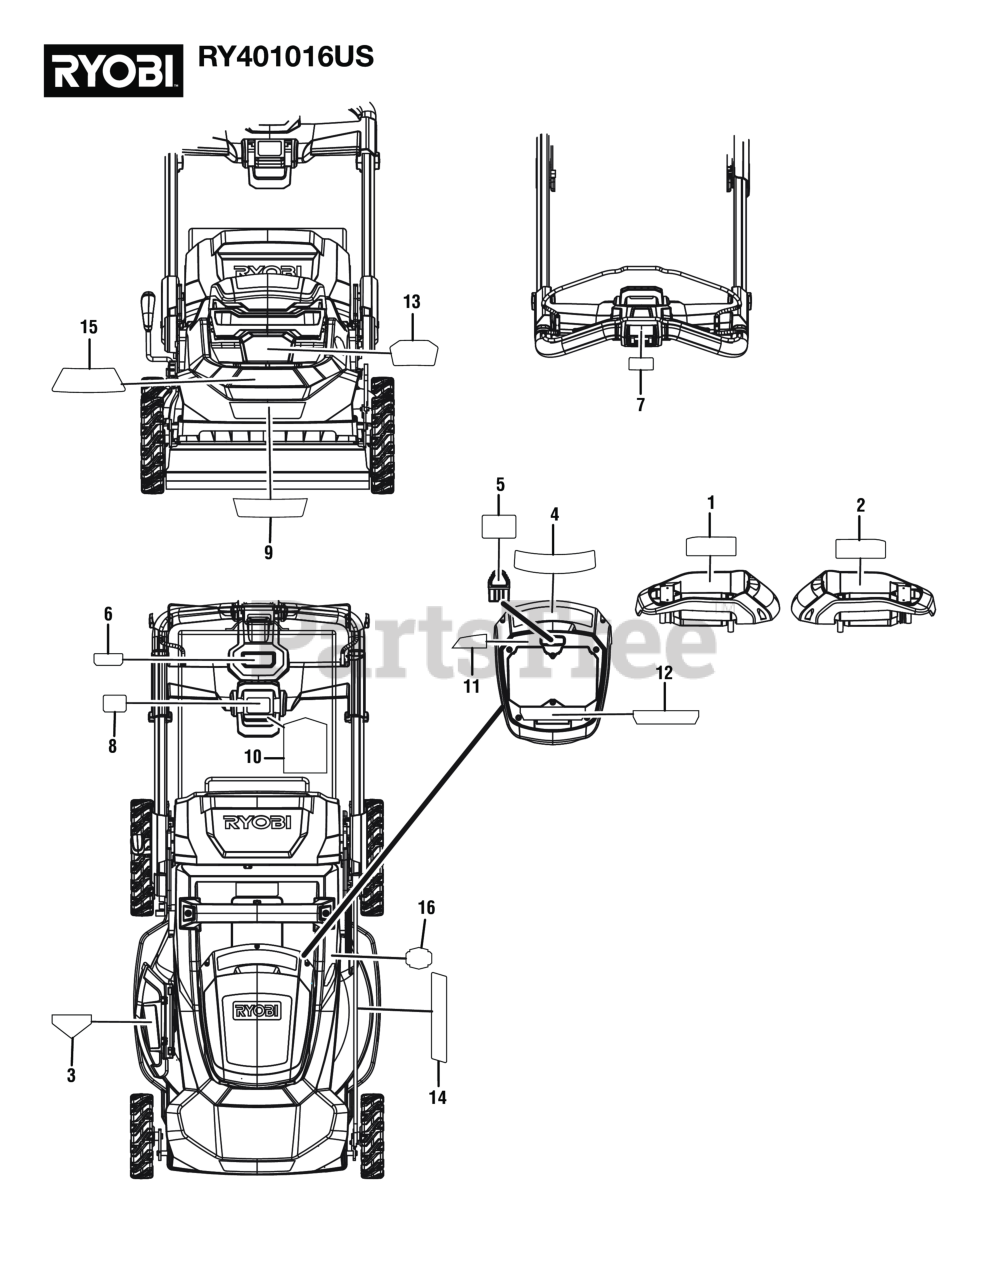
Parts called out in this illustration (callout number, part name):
1	Start Key Warnings Label
2	Spanish Danger Label
3	Danger Label (No Hands/Feet)
4	Main Danger Label (EN/FR)
5	Start Key Battery Port Callout Hangtag
6	RYOBI Logo Label
7	Instructions Label
8	ONE FOLD Logo Label
9	PUSH Front Logo Label
10	Folding Instructions Hangtag
11	QR Code Label
12	Battery Wet Conditions / Data Label
13	40V HP BRUSHLESS Logo Label
14	Right Side Label
15	3-in-1 Cut Label
16	Made in the USA Label
